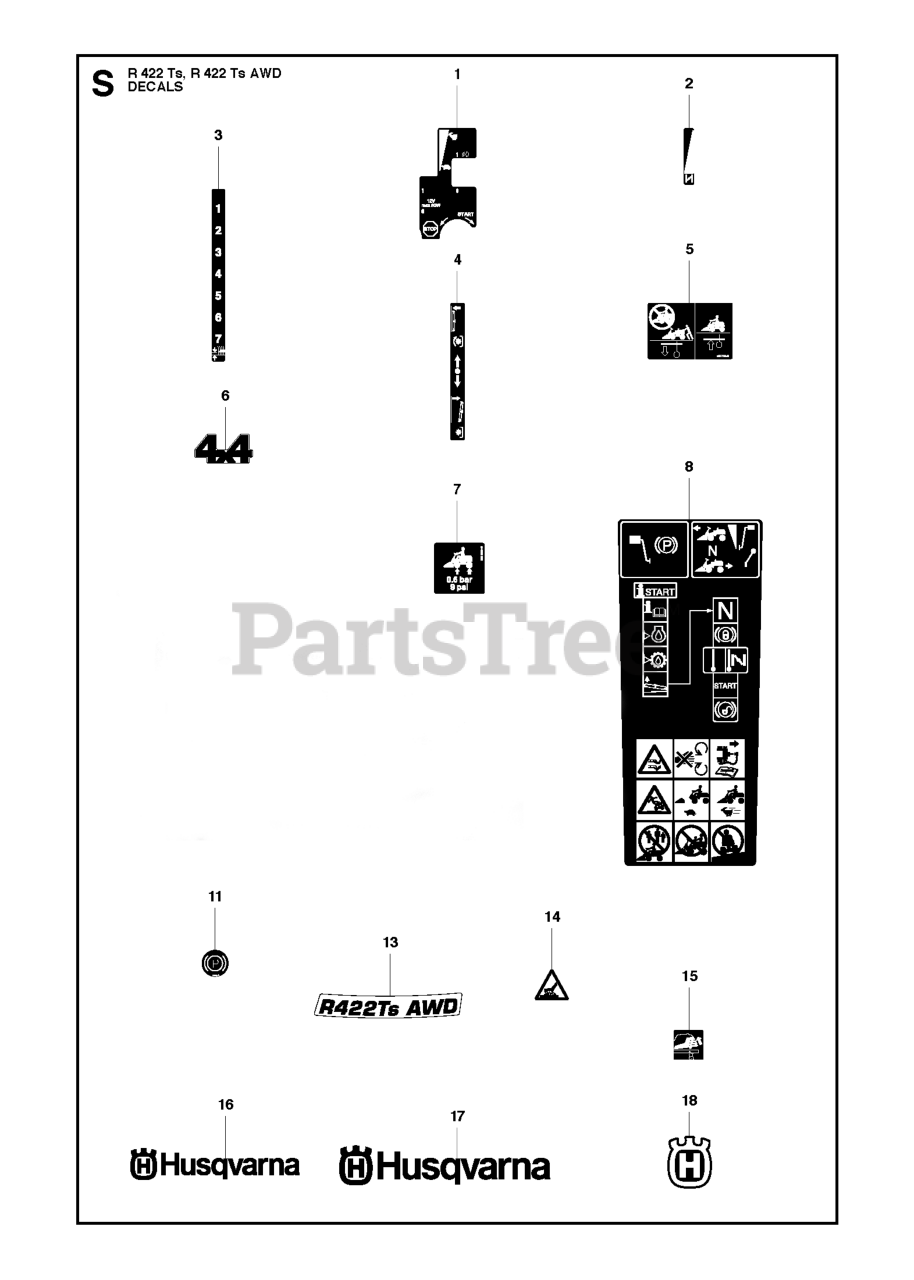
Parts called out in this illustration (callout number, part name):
5	DECAL
6	LABEL
8	Decal - Warning
